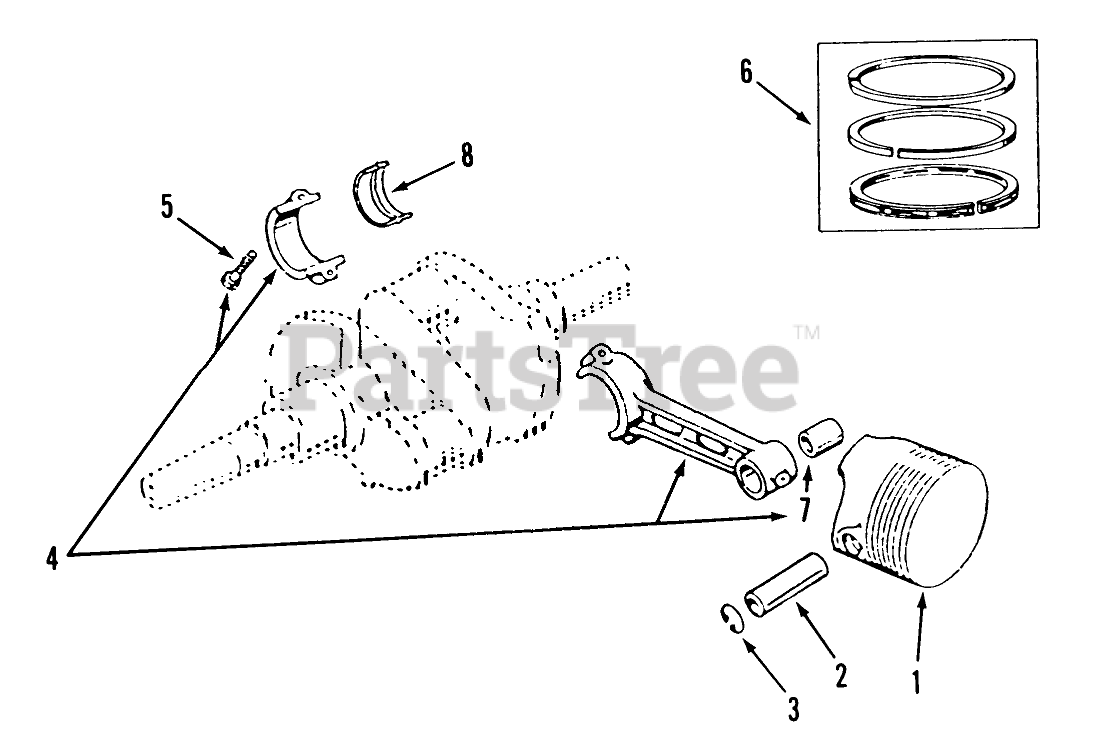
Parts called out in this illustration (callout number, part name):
1	Piston & Pin (Incl. Pin & Retaining Ring) Spec. D Engine
2	PIN - PISTON
3	Retaining Ring
4	Rod-Connecting (Incl. Bolts)
5	BOLT-PLACE
6	Set-Piston Ring Spec. D Engine
7	BUSHING-PISTON PIN
8	Bearing-Connecting Rod, Half
